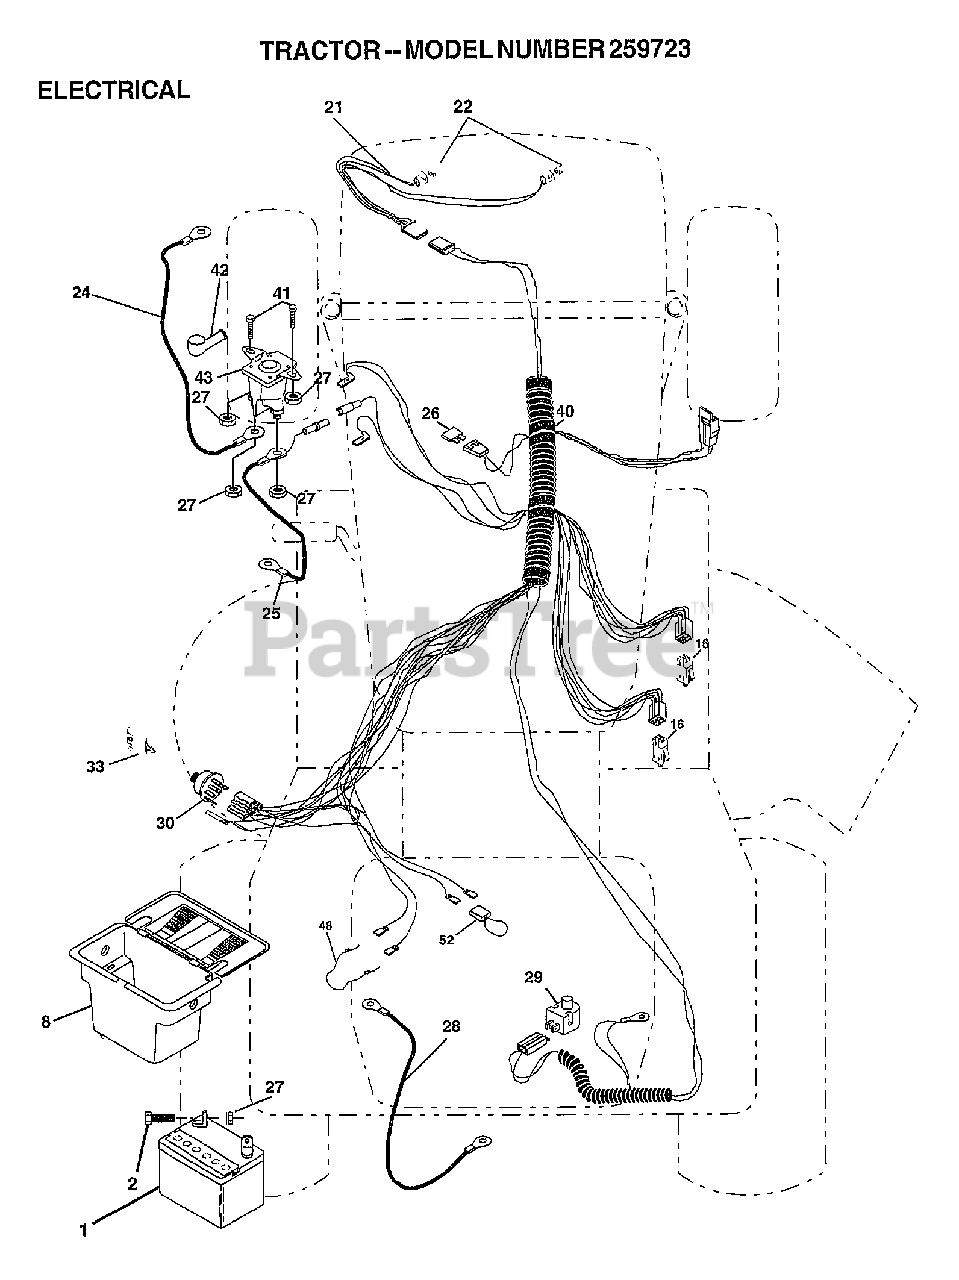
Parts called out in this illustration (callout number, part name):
2	BOLT LT
8	"CASE,BATTERY.MECH"
16	SWITCH INTERLOCK
21	HARNESS.ASM.LIGHT W/4152J
22	HEADLAMP BULB
24	CABLE ASM.
25	CABLE.BTRY.6GA.RD
26	FUSE.15 AMP
27	NUT
28	CABLE T
29	SWITCH SEAT
30	SWITCH.IGN.
33	KEY MLD GEN DELTA
40	HARNESS IGN
41	BOLT HXHD FIN
48	ADAPTER AMMETER
52	PROTECTION LOOP
